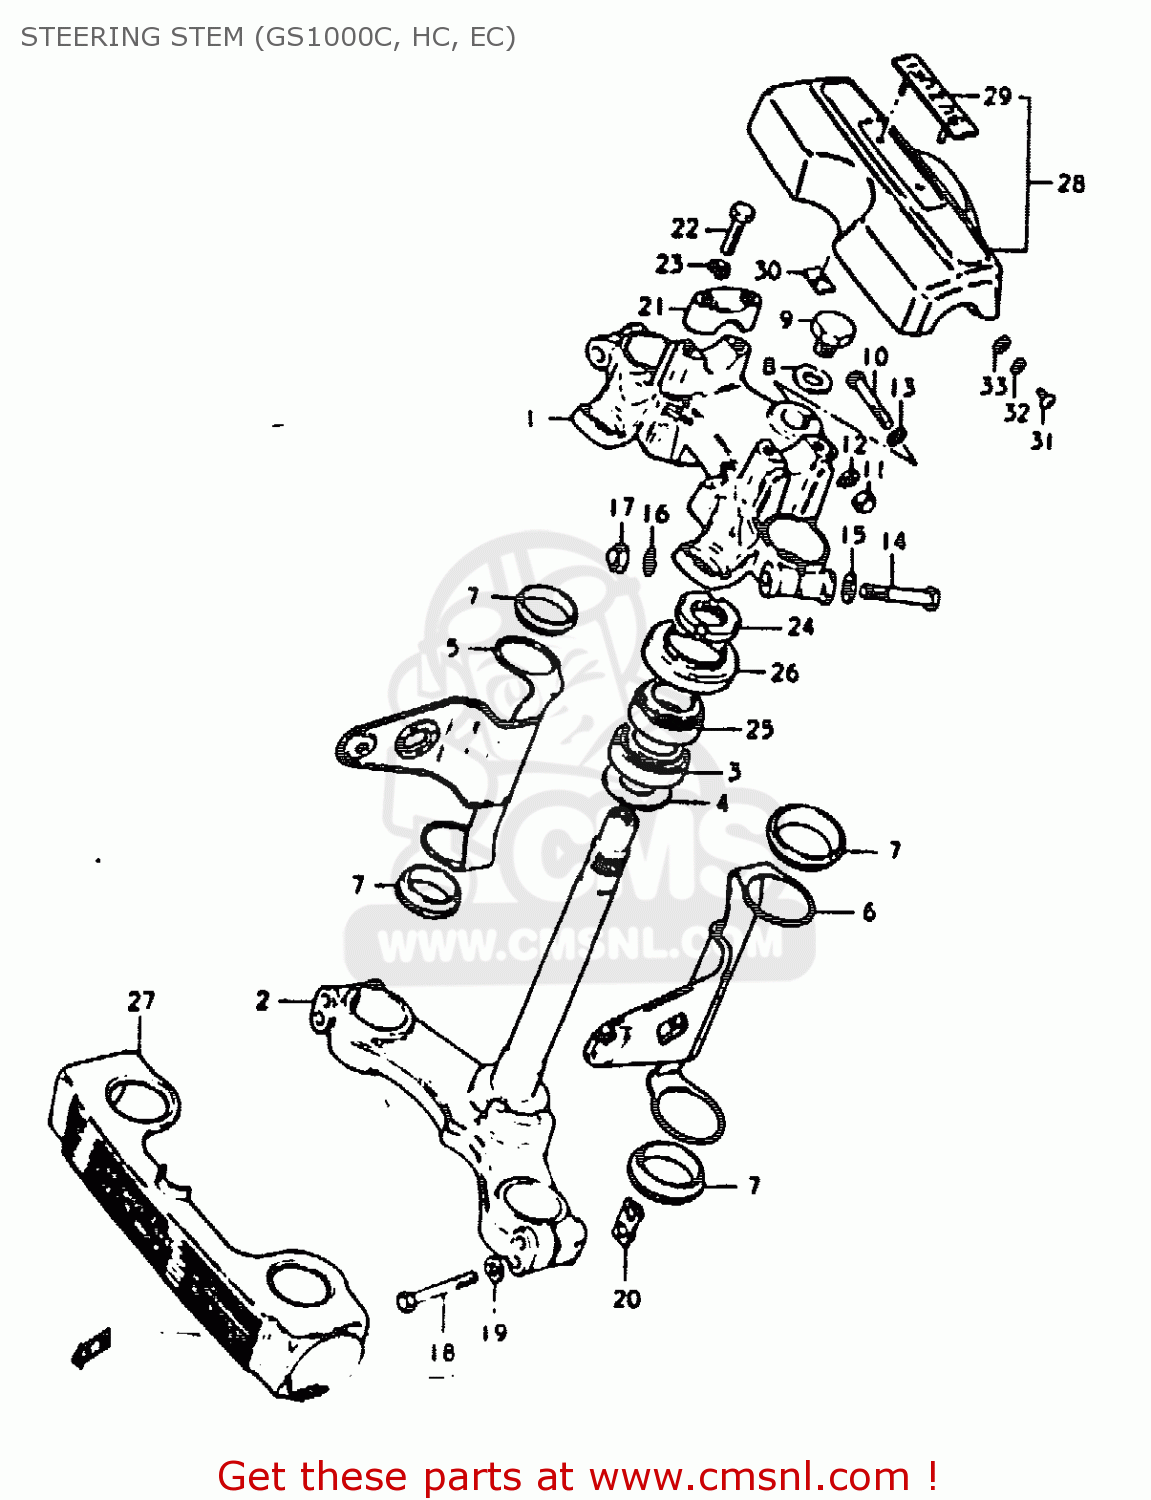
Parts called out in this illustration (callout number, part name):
1	HEAD,STEERING STEM
2	STEM,STEERING
3	BEARING
4	WASHER,THRUST
5	BRACKET,HEADLAMP,RIGHT
6	BRACKET,HEADLAMP,LEFT
7	CUSHION,HEADLAMP BRACKET
8	WASHER
9	BOLT(12X20)
10	BOLT
11	NUT
12	LOCK WASHER
13	WASHER
14	BOLT 10X55
15	WASHER
16	LOCK WASHER
17	NUT, LOWER LH
18	BOLT 8X55
19	WASHER
20	NUT,FR FORK INNER TUBE
21	HOLDER,HANDLE(BLACK)
22	BOLT
23	LOCK WASHER
24	NUT,STEERING STEM(25X44X10)
25	TAPER,ROLLER BEARING
26	DUST SEAL,STEERING,UPPER
27	COVER,FRONT FORK
